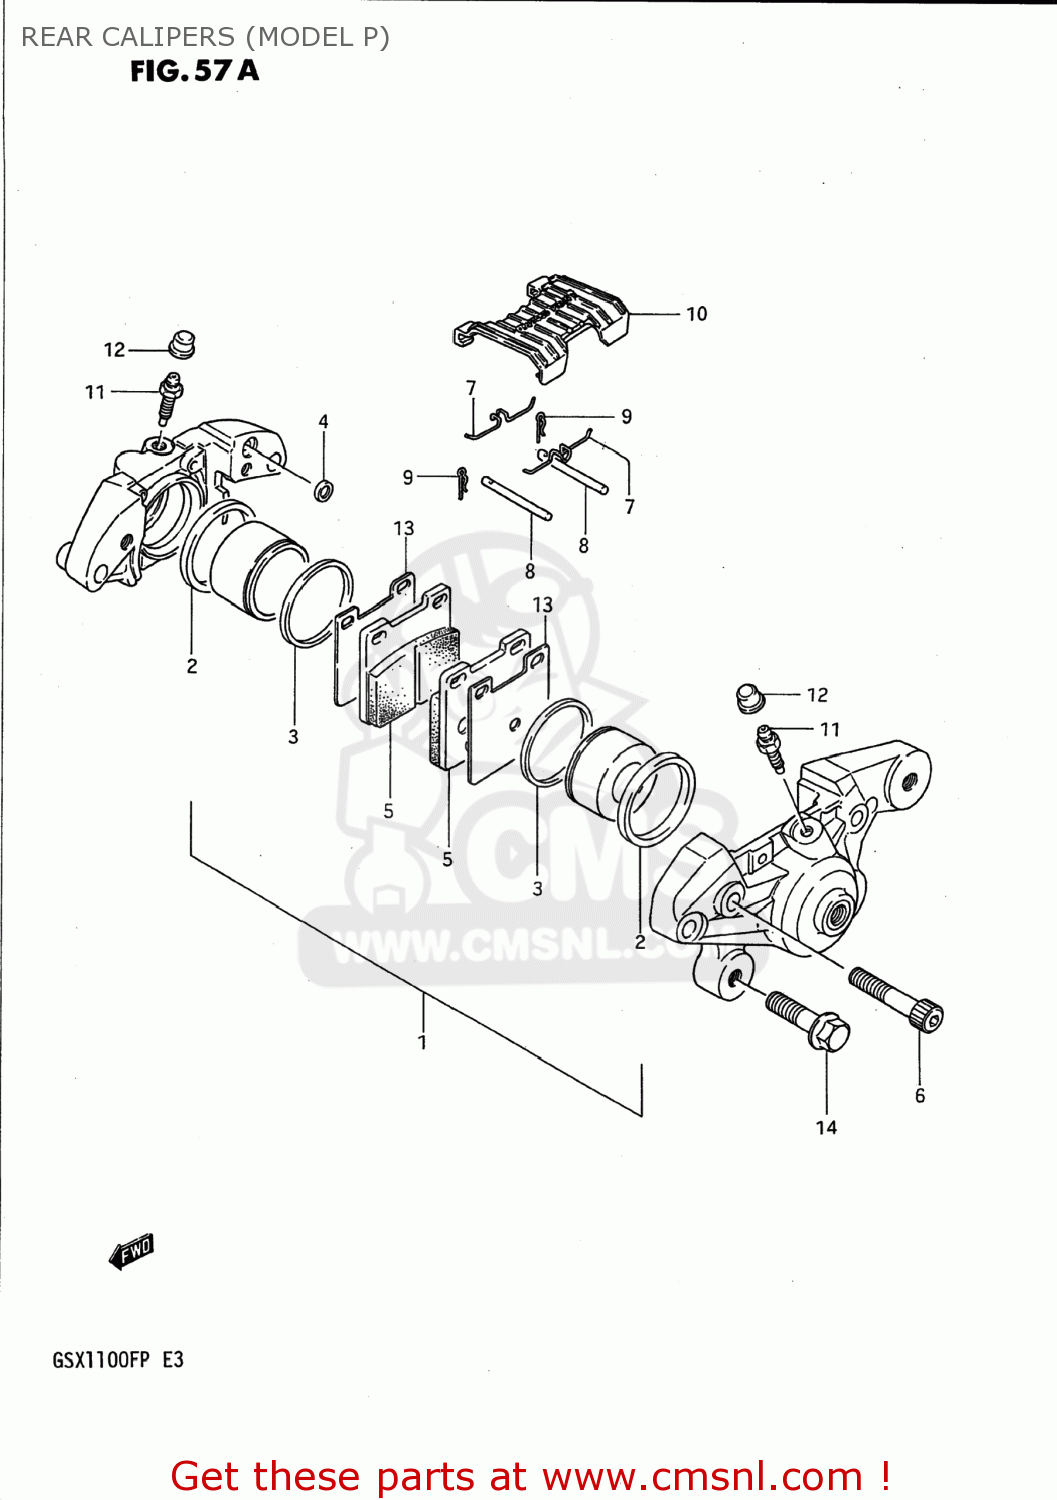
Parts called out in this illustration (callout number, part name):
1	PISTON SET
2	SEAL,PISTON
3	SEAL,WIPER
4	SEAL,JOINT
5	PAD,BRAKE
6	BOLT,CALIPER
7	SPRING
8	PIN,PAD
9	CLIP,PAD PIN
10	COVER,CALIPER
11	BLEEDER
12	CAP,BREATHER
13	SHIM,PAD
14	BOLT 10X30
